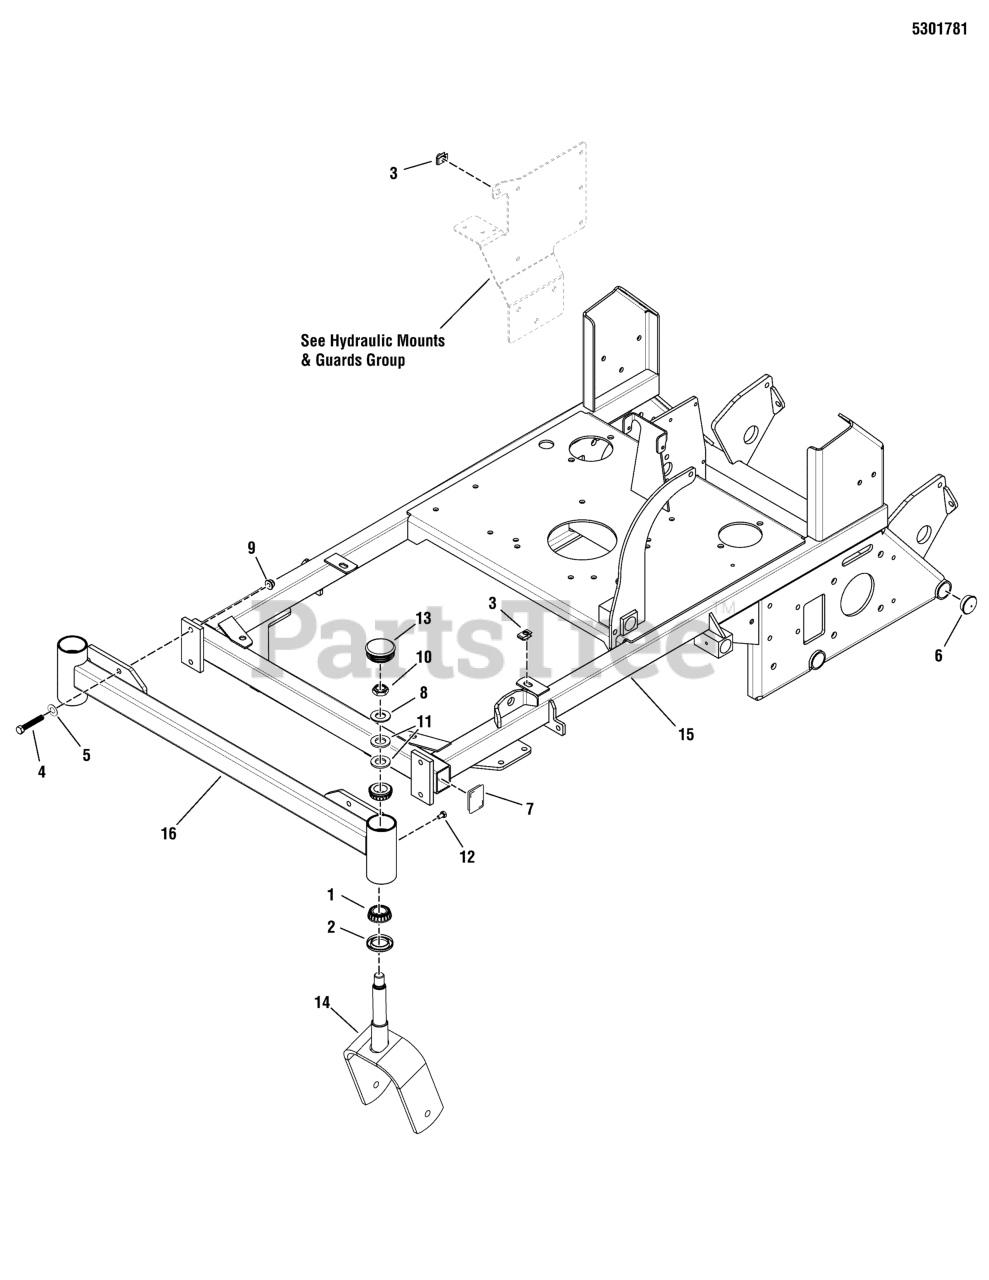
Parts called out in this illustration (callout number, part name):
1	BEARING, TAPERED ROLLER, 1
2	SEAL, GREASE
3	BODY CLIP, 5/16-18-7GA MATERIAL
4	BOLT, 3/8-16 X 1-1/2" GD5 CZ
5	WASHER, 3/8 SAE
6	PLUG, PANEL, 1.25 - BLACK
7	CAP, 1-1/2 X 2 X 11GA, PLASTIC
8	WASHER, 3/4 SAE
9	NUT, 3/8-16 HEX NYLOCK FLANGE
10	NUT, 3/4-16, HEX JAM NYLON LOCK
11	WASHER, BELLEVILLE - 1.500 X .755
12	BOLT, 1/4-28 X 1/2, GD5 YZ
13	CAP, GREASE, LOW PROFILE
14	WELD, CASTER YOKE - RED
15	WELD, MAIN FRAME, S75X - RED
16	WELD, FRONT END PIVOT, S75X - RED
